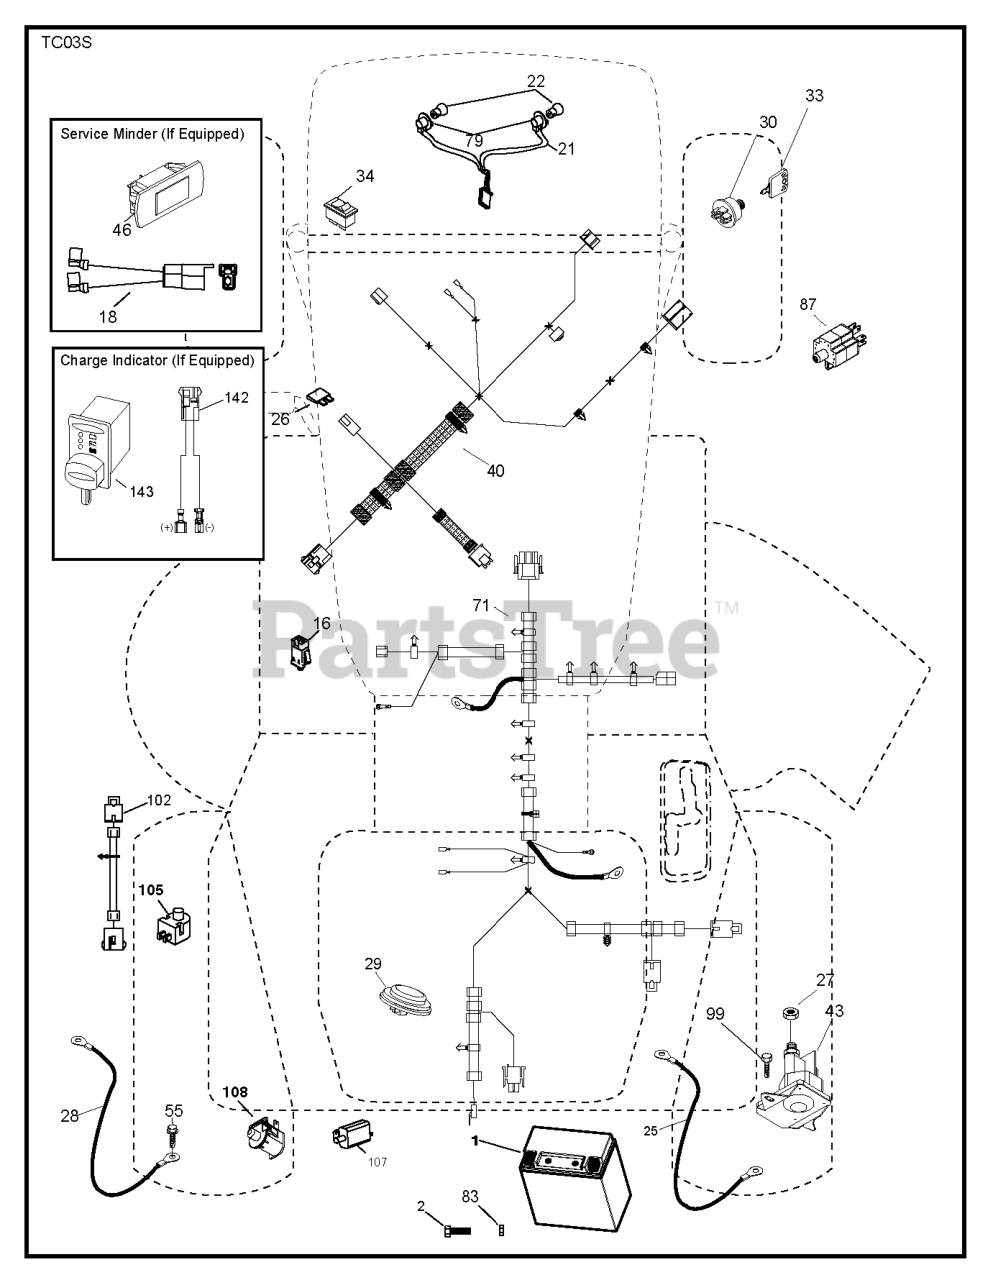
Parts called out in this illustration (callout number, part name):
1	BATTERY BATTERY 14AH 12V LEOC
2	SCREW.HEX.HEAD.CAP.M6 X1.12W
16	SWITCH INTERLOOK PUSH-IN
21	HARNESS.LIGHT W/4152J BULBS
25	CABLE.RED.8AWG.TCRD.GEN1
26	FUSE 20AMP
27	NUT
28	CABLE.BLACK.8AWG.TCRD.GEN1
29	SWITCH.SEAT.DELTA.OPC.
30	SWITCH.IGN.DELTA.W.LGH.ROS
33	KEY.CHAIN.BLISTER.PACK.GEN.INT
40	HARN.DASH.CRD.CC.SQ.RDSTRT
43	SOLENOID.STARTER.BRASS.PLUNGER
55	SCREW 5/16"
71	HARNESS.CHASS.CRD.TEX.RDY.STRT
79	BULB HOLDER ASM.
83	NUT NUT SQUARE
87	RP SWITCH.RAILMOUNT.NO-NC-NC
99	SCREW
102	HARNESS ASSY
105	REVERSE SWITCH
107	.WITCH.FULL BAGGER.INDICATOR
108	SWITCH.SNAPMOUNT.NC
142	CHARGE.PORT.PIGTAIL HARNESS
143	CHARGE.PORT
